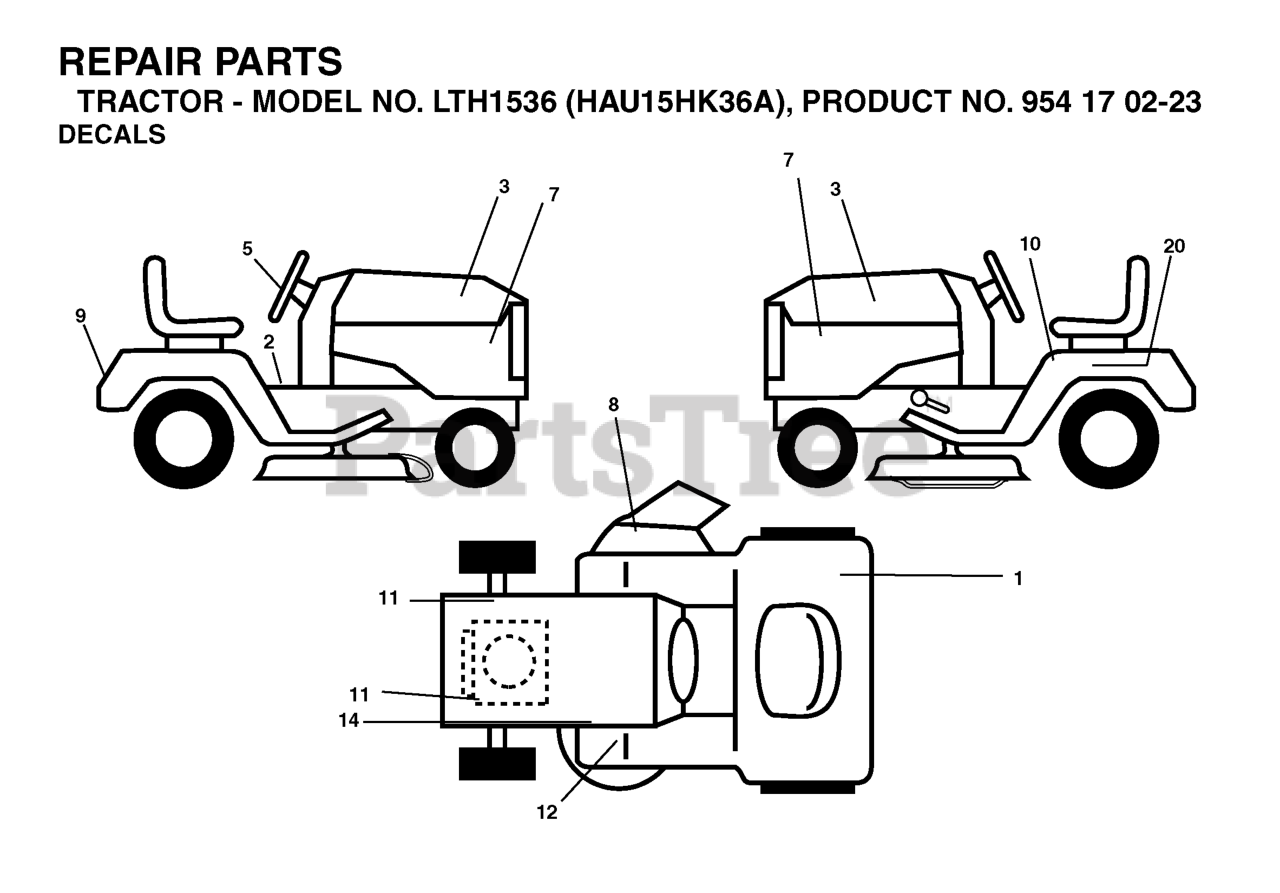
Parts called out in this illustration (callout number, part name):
1	DECAL
2	DECAL PARK BRAKE
5	DECAL.STEERING.HUSQ.BLUE
7	DECAL.HOOD.HUSQVARNA.INTERNATI
8	DECAL.INTERNATIONL.CUTFINGER
10	DECAL READ OWNER'S MAN SYMS
12	DECAL
14	DECAL V-BELT SCHEMATIC
20	DECAL BTRY SYMBOLS
